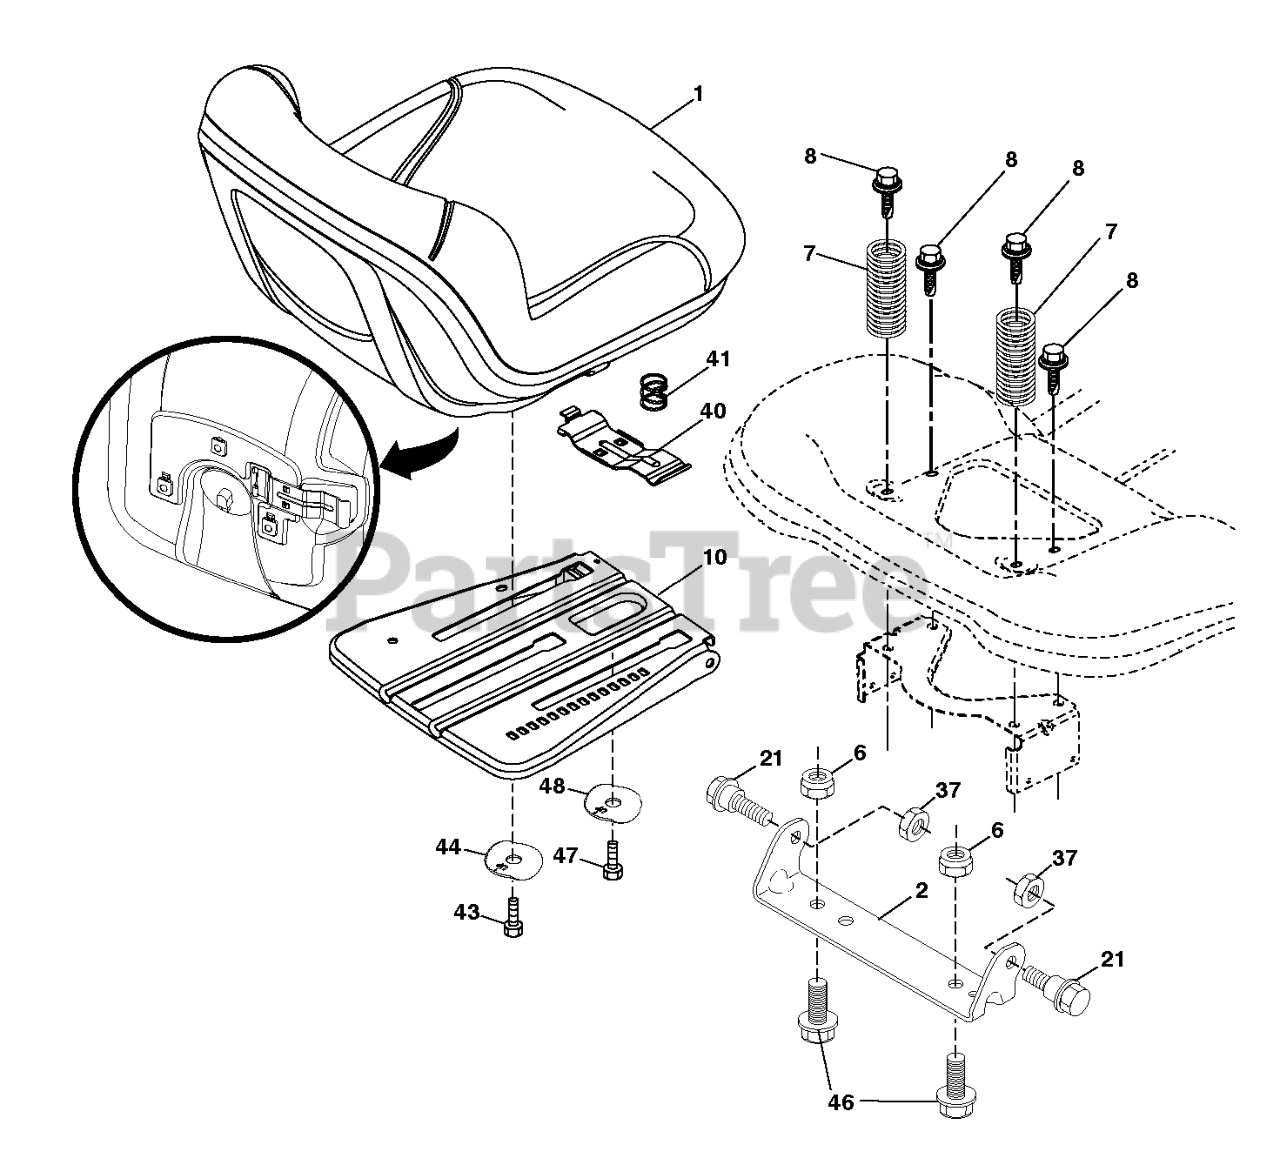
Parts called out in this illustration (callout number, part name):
1	SEAT.TH130.GREY.HUSQ.TEX
1	SEAT.TH110.HUSQ.TEX.GREY
2	BRKT.PIVOT.FENDER
6	NUT
7	SPRING.COMPRESS.SEAT.TAPERED
7	SPRING.COMPRESSION.SEAT.BLACK
8	BOLT.5/16-18UNCX3/4 W/SEMS.BLK
10	KIT.PLATE.SEAT
21	BOLT.5/16-18X5/8.SHOULDER
37	Hardware
40	HANDLE.SLIDE.SEAT.TEX.BLACK
41	SPRING.LATCH.SEAT.TEX
44	WASHER 13/32 X 2-3/8 X 12GA
44	WASHER.WINGED.3/8ID.1.5OD
46	BOLT.3/8-16X1;1.25OD.WSHR.SEMS
48	WASHER.WINGED.3/8ID.1.5OD
